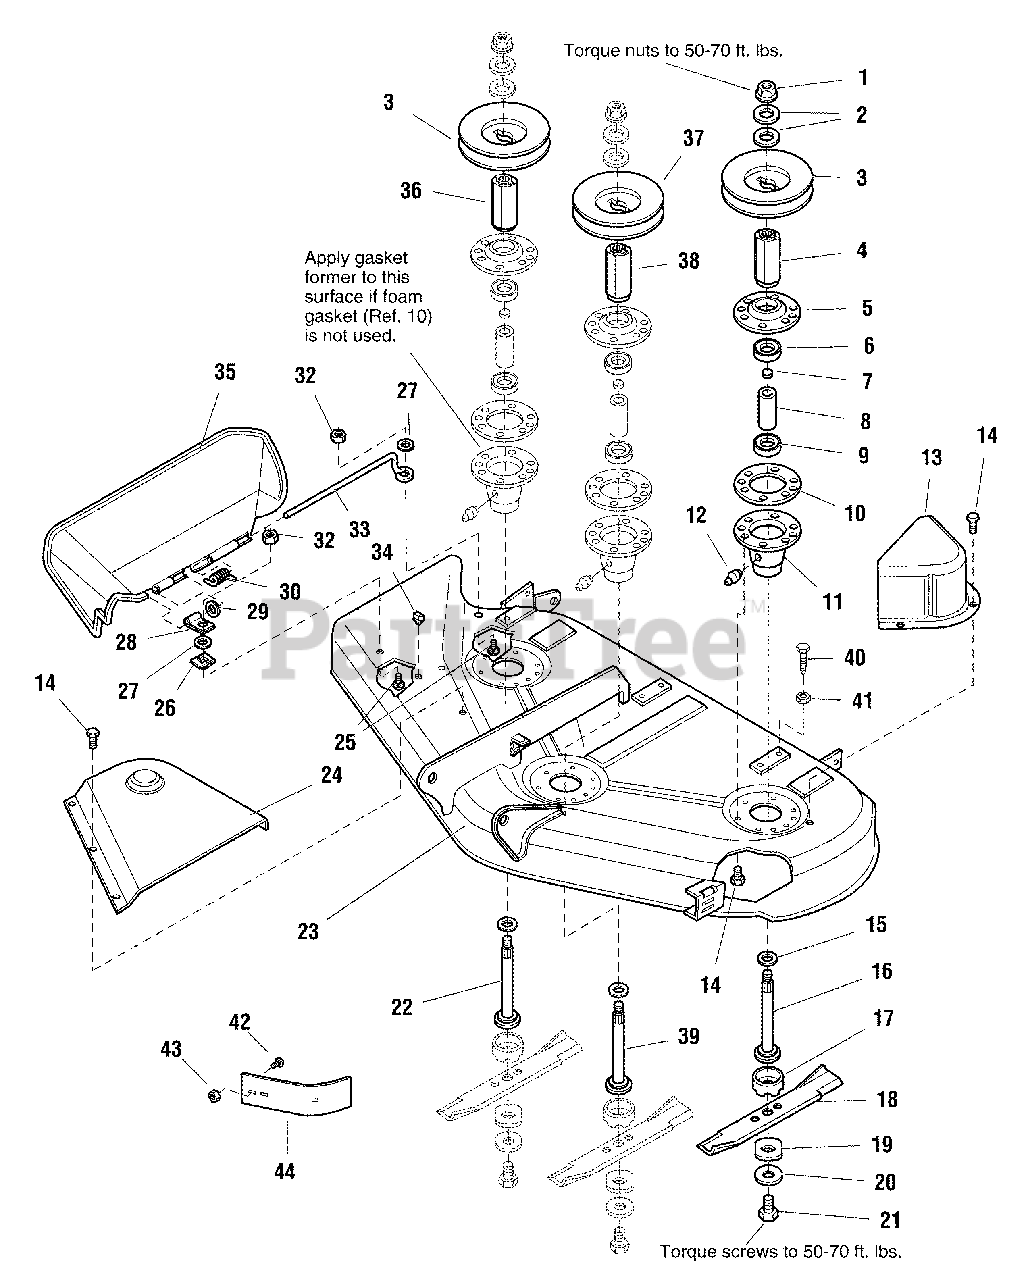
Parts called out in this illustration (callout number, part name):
1	NUT, Hex, Flange, 9/16-8
2	WASHER, Belleville
3	PULLEY, RH Arbor & LH Arbor, 4-1/2 OD
4	HUB, Adapter, LH
5	COVER, Arbor Housing
6	BEARING, Upper
7	SPACER, Sleeve, Upper Bearing
8	SPACER, Arbor, Internal
9	BEARING, Lower
10	GASKET, Foam
11	HOUSING ASSEMBLY, Arbor Bottom, w/Lube Fitting
12	FITTING, Grease
13	COVER, Arbor LH
14	CAPSCREW, Taptite Hex Washer Head, 5/16-18 x 3/4
16	SHAFT, Arbor LH
17	SHIELD, Grass, Lower
18	BLADE, Mower, 16-1/8
19	WASHER, Hex
20	WASHER, Spring
21	CAPSCREW, Hex, Head, 7/16-14 x 1-1/4
22	SHAFT, Arbor (RH)
23	HOUSING ASSEMBLY, Orange
23	HOUSING ASSEMBLY, Black
24	COVER, Arbor (RH)
25	CARRIAGE BOLT, 1/4-20 x 7/8
26	NUT, Push
27	WASHER, Plain, 1/4
29	WASHER, Plain, 5/16
30	SPRING, Deflector Retaining
32	NUT, Hex, 1/4-20 ESNA
33	ROD, Deflector, Front
34	PLUG, Hole *
35	DEFLECTOR, Plastic
36	HUB, Pulley, RH
37	PULLEY, Arbor (Center)
38	HUB, Pulley (Center)
39	SHAFT, Arbor (Center)
40	CAPSCERW, Hex Head, Taptite, 5/16-18 x 1/2
41	NUT, Hex Whiz Lock, 5/16-18
42	BOLT, Round Head 3/8-18 x 3/4
43	NUT, Hex Flange Whiz Lock 5/16-18
44	BAFFLE, Blowout
